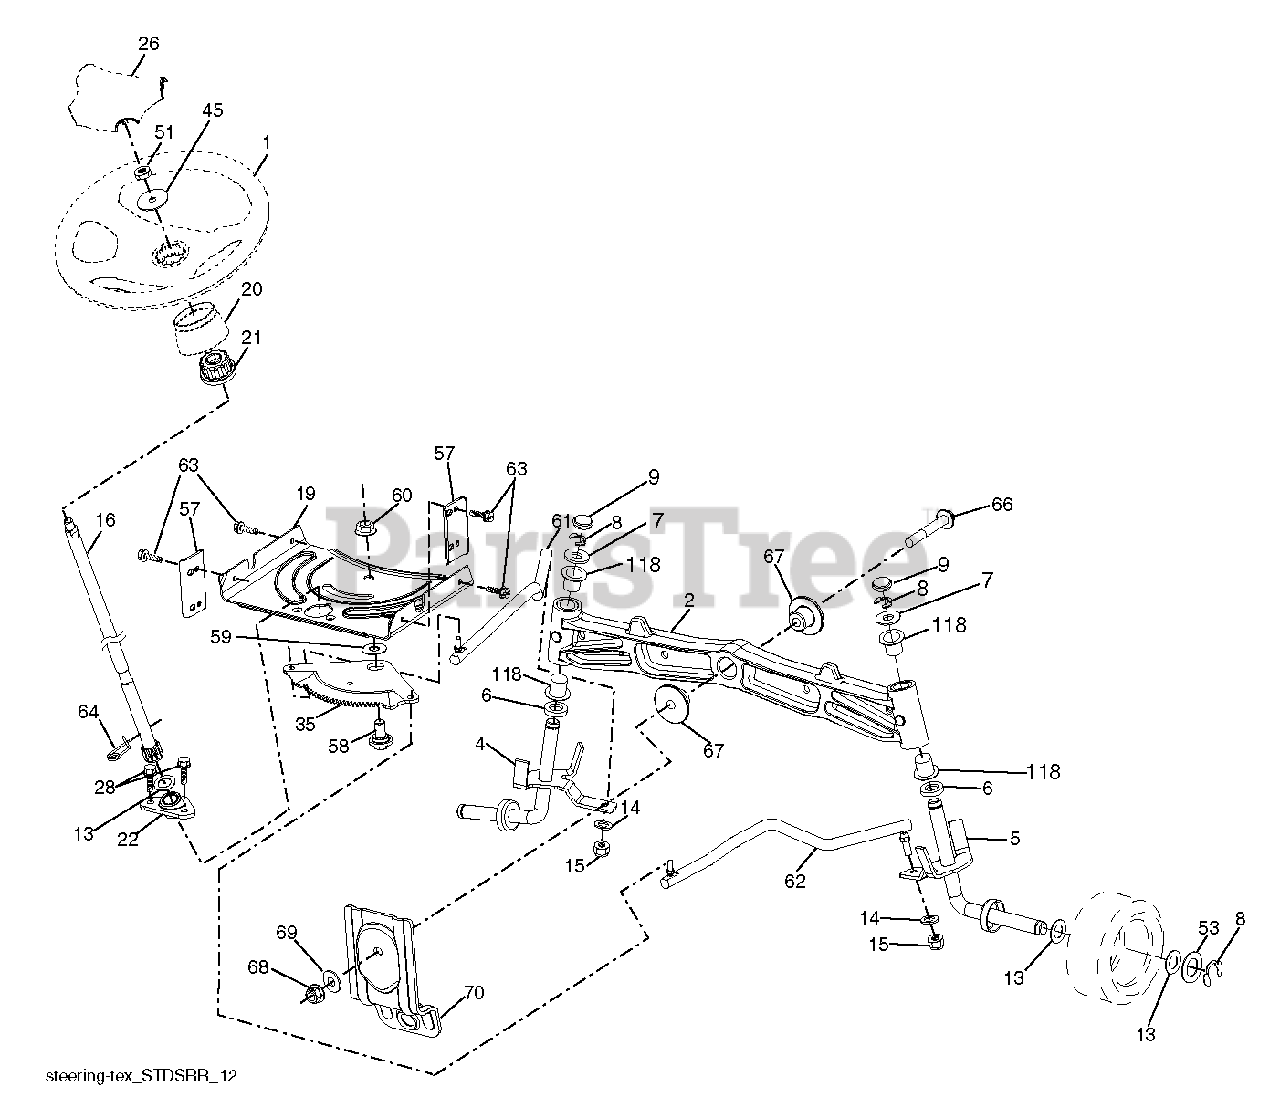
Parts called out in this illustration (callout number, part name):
1	WHEEL.STEERING.PREM.2.BLK
2	AXLE.SVC.ASM CAST IRON.TEX
4	SPINDLE.WELDED.LH.15"TEX
5	SPINDLE.WELDED.RH.15"T
8	RING CLIP
9	CAP.SPINDLE
14	WASHER, LOCK 3/8
15	NUT CROWNLOCK 3/8-24
16	SHAFT.STEER.STEALTH.DD
19	PLATE.STEER.DDL.NLT/NG
21	ADAPTER, WHEEL STNG..
22	STEERING.SUPT.LOWER.
26	INSERT.CAP.STRG.WH.BLACK
28	SCREW, 3/8-16X3/4
35	GEAR.SECTOR.PLATE.DDL.
45	WASHER 9/16"ID, 2 3/8"OD
51	NUT.HEX.1/2-20
53	WASHER.HARDENED
57	BRACKET.UPSTOP.TEX
58	BOLT.SHOULDER.SECTOR.P
59	WASHER.THURST.SECTOR.S
60	NUT FLANGE LOCK 5/8-11
61	DRAGLINK.LH.BALLSTUD.D
62	DRAGLINK.RH.BALLSTUD.D
63	SCREW
64	RETAINER.CLIP.SPRING.S
66	BOLT HEX FGHD 7/16-14 X 3 SERR
67	BUSHING.PM.FRONT AXLE
68	NUT.LOCK.FLANGE.7/16
69	WASHER.1.5X.505X.118
70	BRKT.DECK.SUSPENSION.F
118	BUSHING, AXLE CAST
